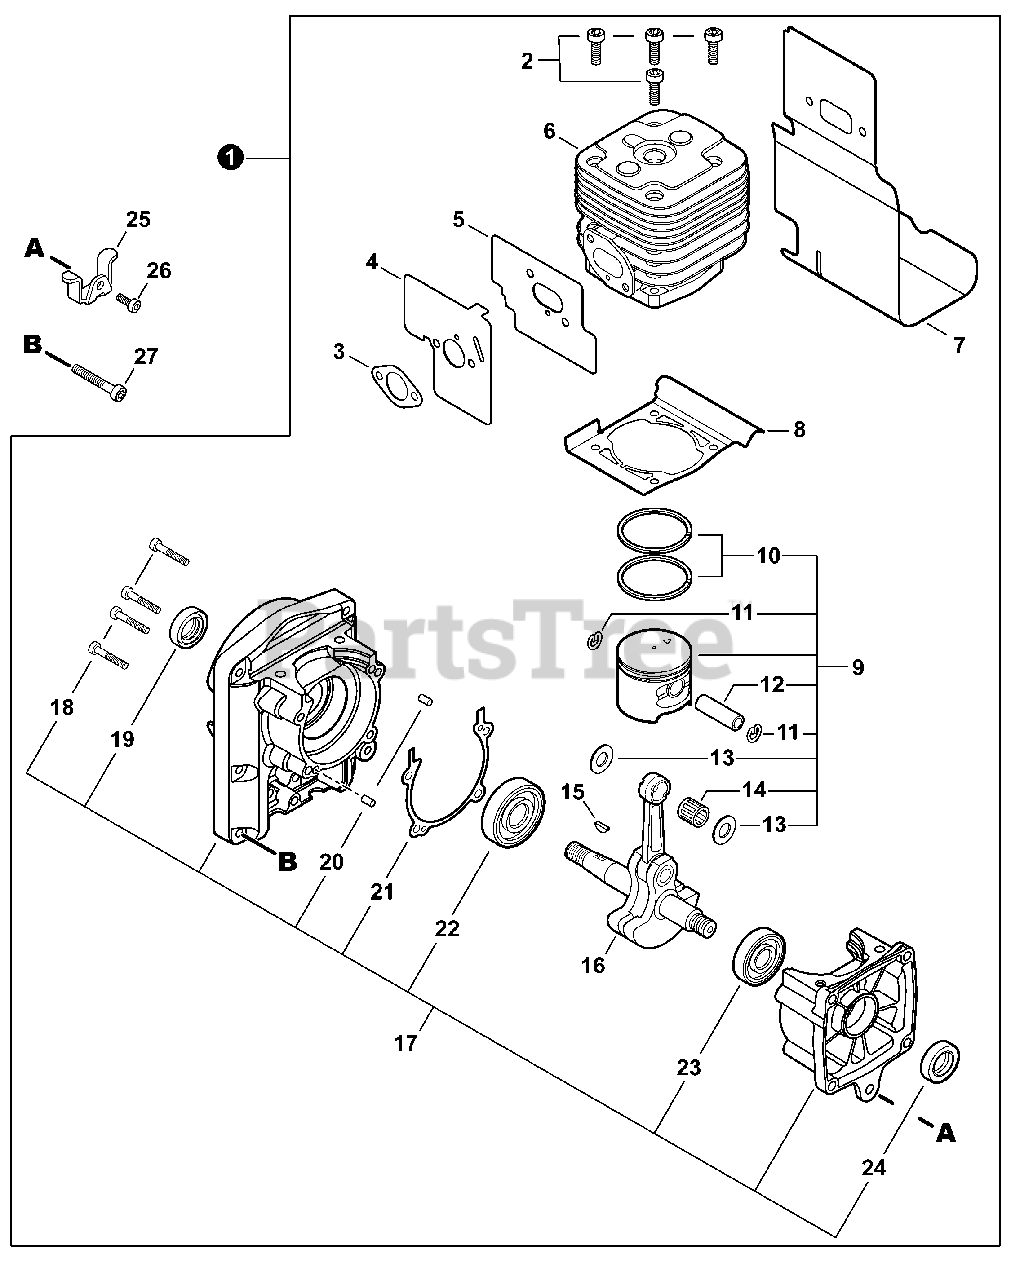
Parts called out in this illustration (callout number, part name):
1	SHORT BLOCK
2	BOLT, TORX 5×20
3	GASKET, INTAKE
4	GASKET, INTAKE
5	HEAT SHIELD, INTAKE
6	CYLINDER
7	HEAT SHIELD, EXHAUST
8	GASKET, CYLINDER
9	PISTON KIT
10	RING, PISTON
11	RING, SNAP Ø10
12	PIN, PISTON 10
13	WASHER, THRUST
14	BEARING, NEEDLE 10
15	KEY, WOODRUFF 3×14
16	CRANKSHAFT
17	CRANKCASE KIT
18	BOLT, TORX 5×30
19	SEAL, OIL
20	PIN, LOCATING 4×8
21	GASKET, CRANKCASE
22	BEARING, BALL 6302 C3
23	BEARING, BALL 6202
24	SEAL, OIL 15
25	CUSHION 5
26	BOLT, TORX 5×12
27	BOLT, TORX 5×30
